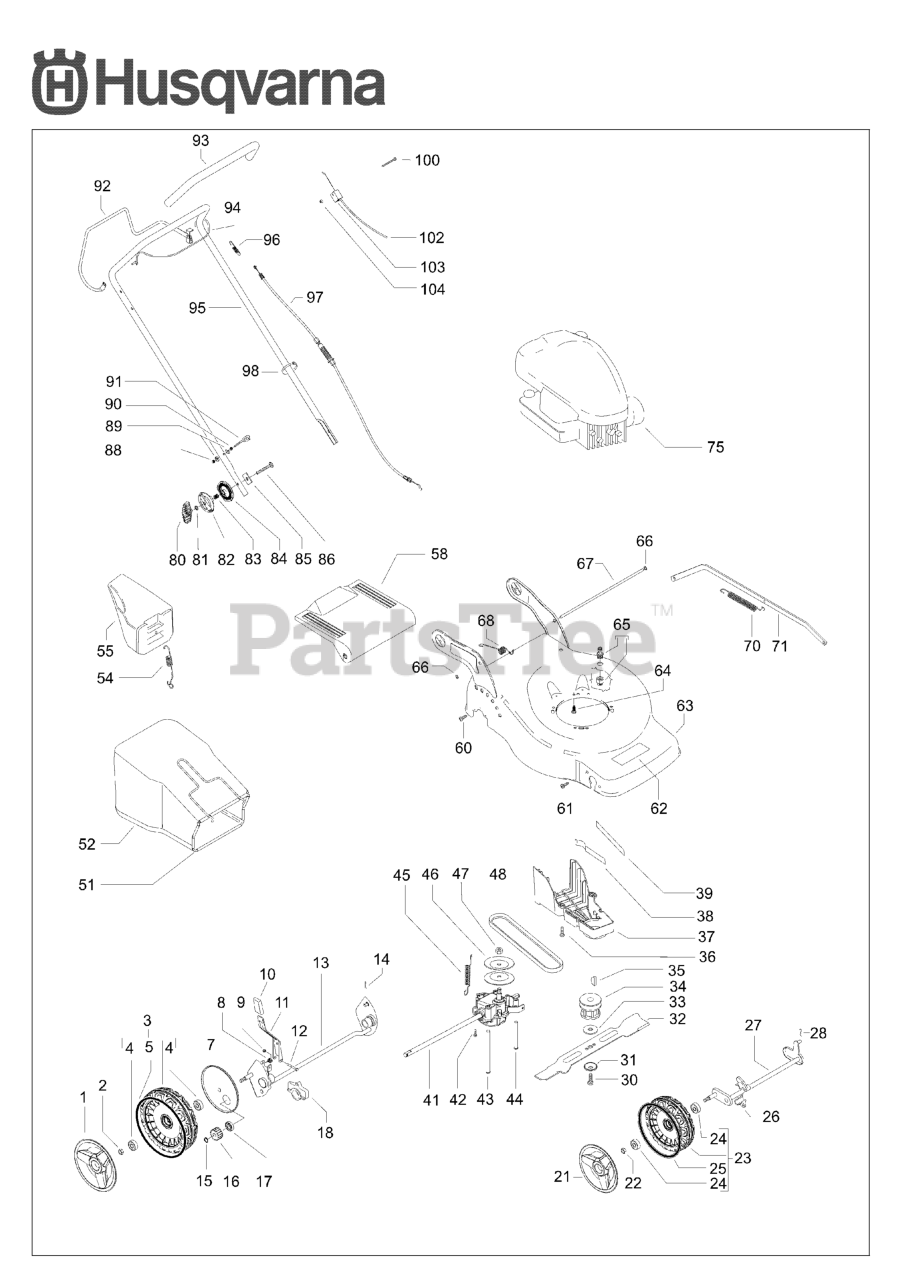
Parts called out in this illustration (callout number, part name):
11	LIFTING LEVER ASSY FOR REAR AX
32	MOWER BLADE COMBI
102	BRAKE WIRE
